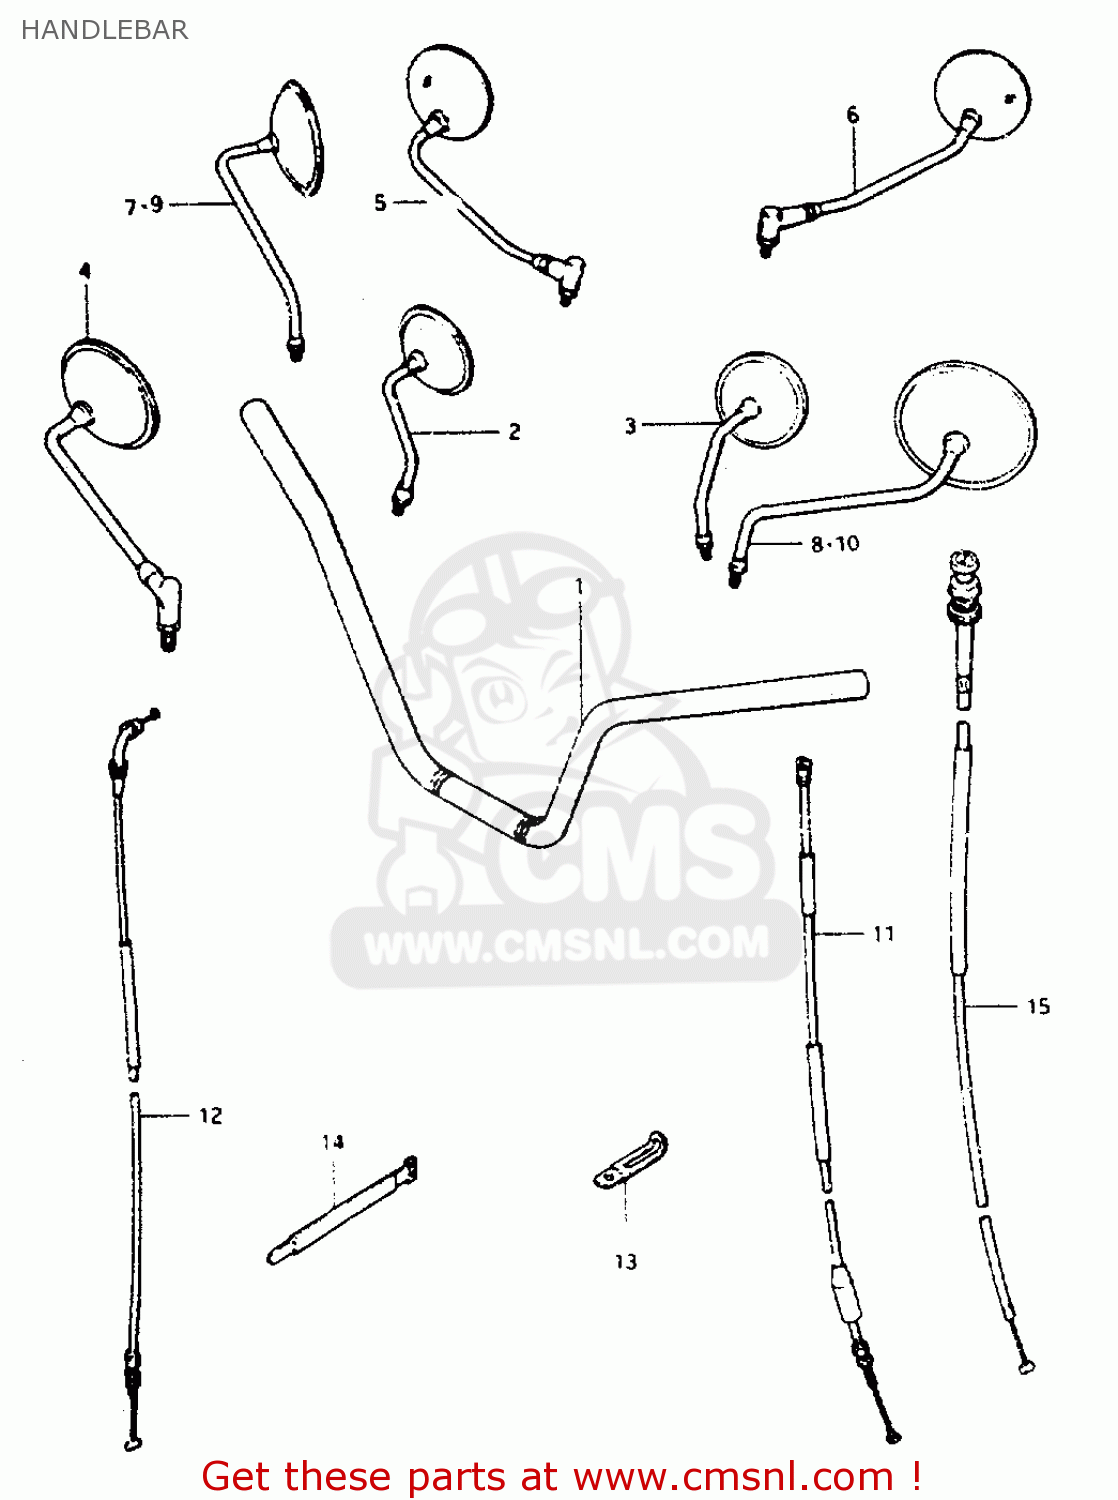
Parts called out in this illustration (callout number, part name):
1	HANDLEBAR
4	MIRROR, REAR VIEW
11	CABLE,CLUTCH
12	CABLE ASSEMBLY,THROTTLE
13	CLAMP
14	CLAMP
15	CABLE ASSEMBLY,STARTER
